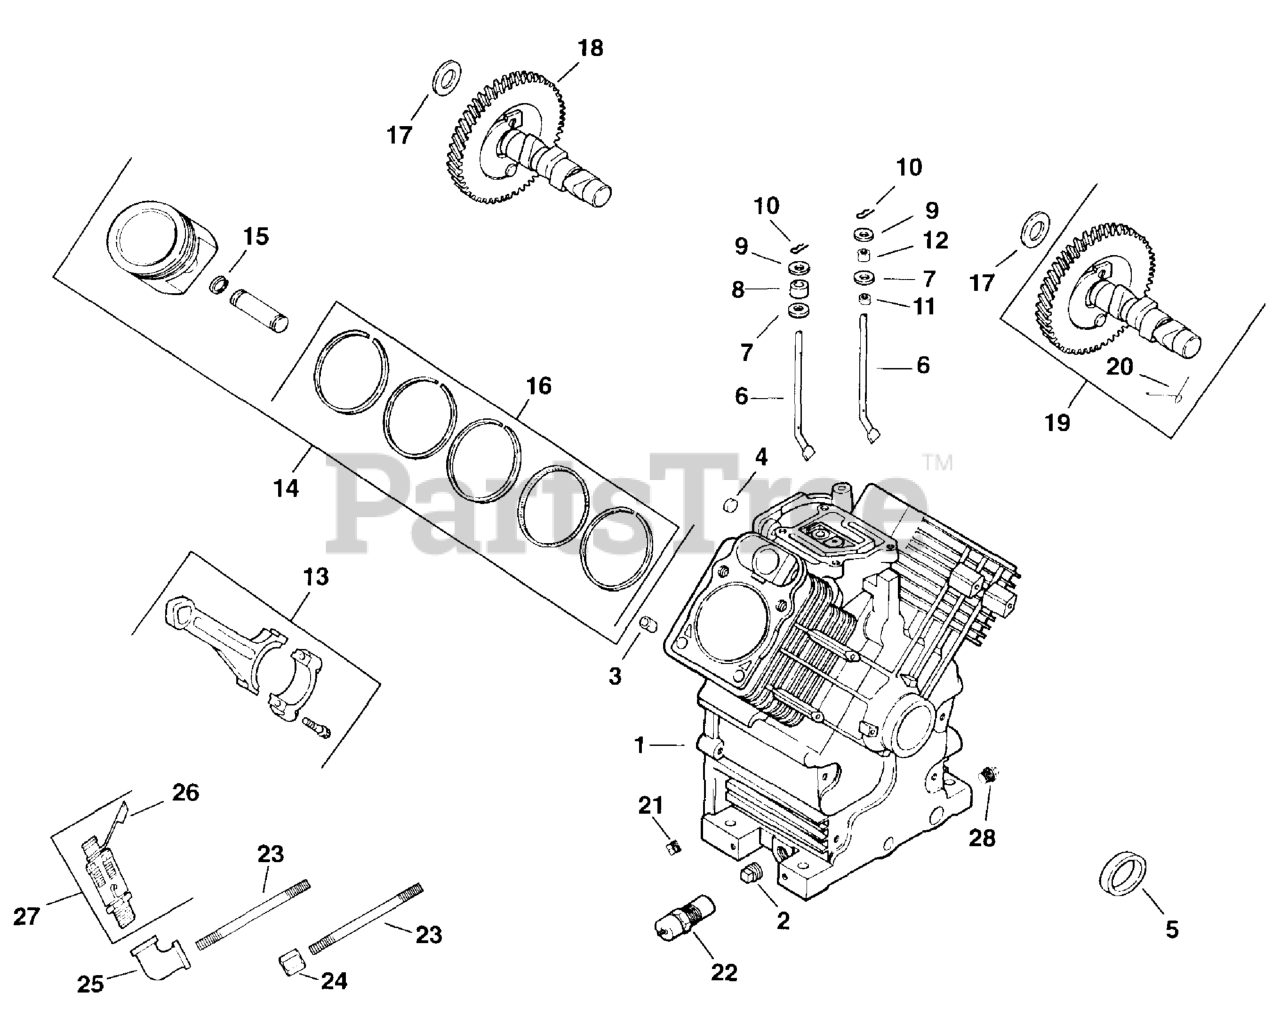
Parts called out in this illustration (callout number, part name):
1	CRANKCASE
4	PLUG, CUP
5	SEAL, OIL FRONT-USE 24 032 19-S
6	SHAFT, GOVERNOR CROSS - (#DSC)
7	WASHER, FLAT 1/4"
8	SEAL, GOVERNOR CROSS SHAFT
13	ROD, CONNECTING ASSY STD-USE 24 067 28-S
13	ROD,CONNECT ASSY.25 U/S-USE 24 067 17-S
14	PISTON W/RINGS (STYLE A)(STD) USE 24 874 17-S PISTON
14	PISTON W/RINGS (STYLE A)(.25) USE 24 874 18-S PISTON
14	PISTON W/RINGS (STYLE A)(.50) USE 24 874 19-S PISTON
15	RETAINER, PISTON PIN
16	RING SET-USE 24 108 24-S
16	RING SET-USE 24 108 13-S
17	SHIM, CAMSHAFT (WHITE .028")
17	SHIM, CAMSHAFT (BLUE .03")
17	SHIM, CAMSHAFT (RED .032")
17	SHIM, CAMSHAFT (YELLOW .034")
17	SHIM, CAMSHAFT (GREEN .036")
17	SHIM, CAMSHAFT (GRAY .038")
17	SHIM, CAMSHAFT (BLACK .04")
18	KIT, CAMSHAFT USE 24 012 23-S
28	PLUG, HD PIPE 3/8"
